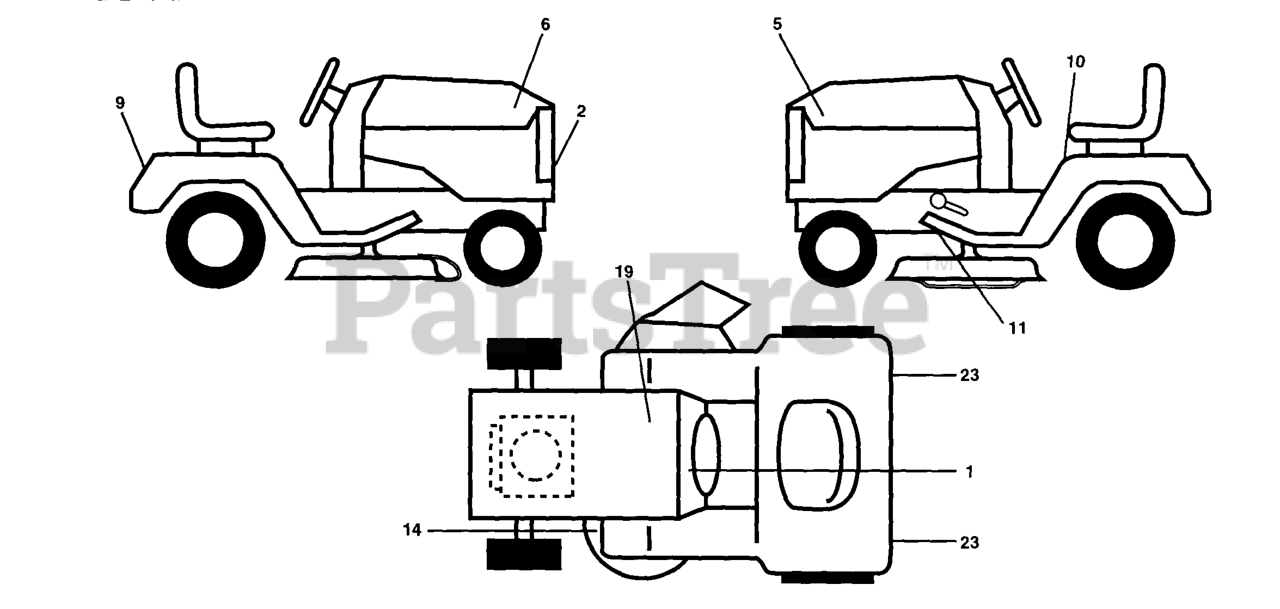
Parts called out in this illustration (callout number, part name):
2	DECAL.GRILLE.HUSQ
5	DECAL HOOD LH GT200
6	DECAL HOOD RH GT200
9	DECAL FENDER HUSQ
10	DECAL CAUTION
19	DECAL BTRY SYMBOLS
23	REFLECTOR-TAIL YT
